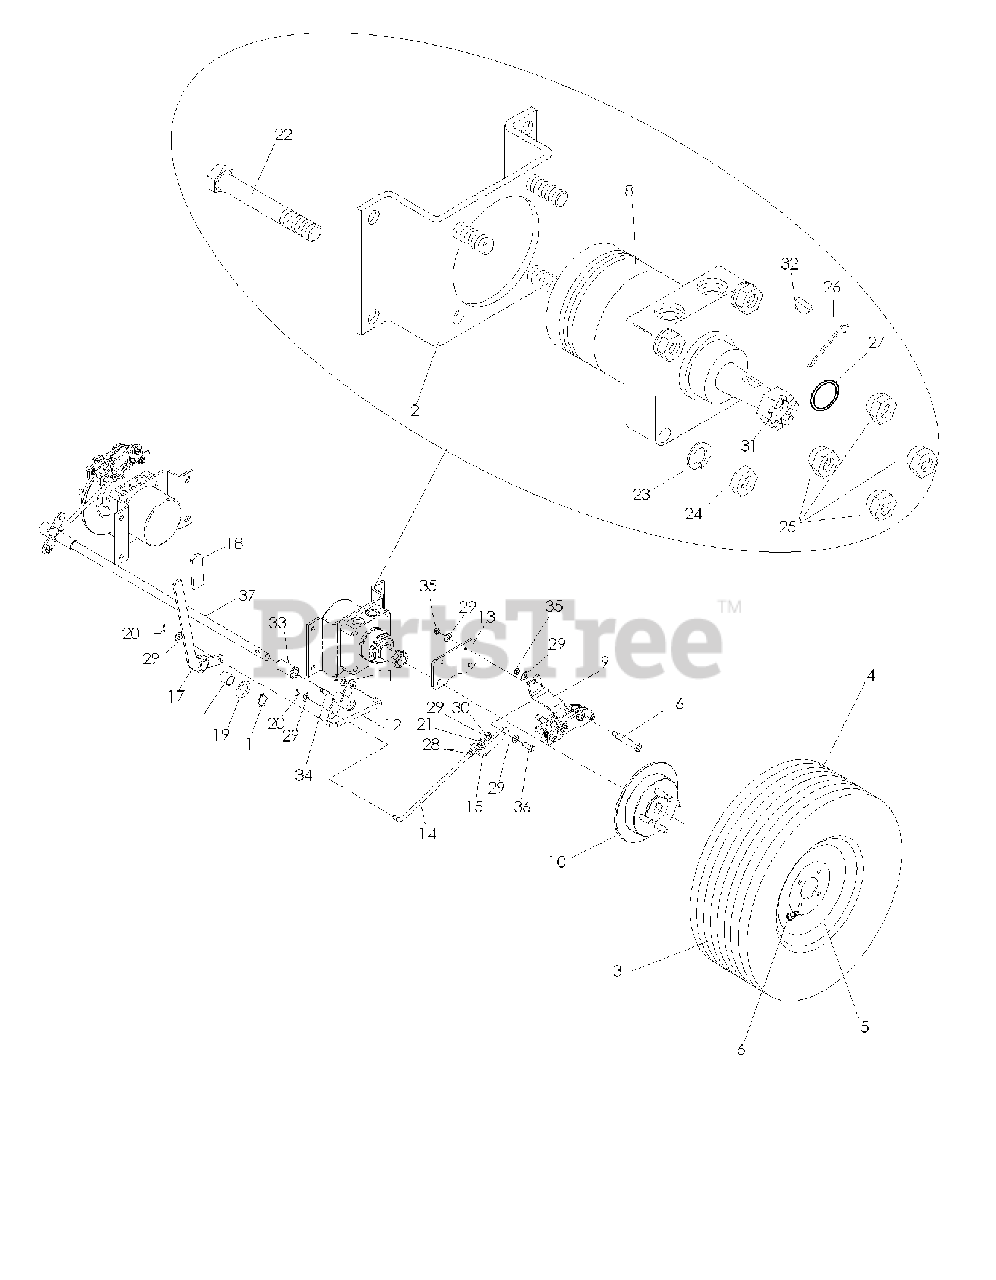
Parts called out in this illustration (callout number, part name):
1	RETAINING RING, 7/8"
2	MOTOR STANDOFF - PAINTED
3	TIRE ASSY 24-12
3	TIRE WHEEL ASM 23 X 9.5-12
4	TIRE.TURF.MASTER.24X12-12
5	RIM 2.5" NEG OFFSET 8.5" WIDE
6	VALVE STEM TR-412
7	BUSHING
8	TL15 WHEEL MOTOR
9	CALIPER ASSEMBLY
11	BELLCRANK, BRAKE
12	LINKAGE, BRAKE
13	PLATE, BRAKE
14	LINKAGE, REAR BRAKE
15	BRACKET, L
16	SB 3/8-16 X 2-1-1/2 SKT HDD ZD
17	LEVER, BRAKE WELDMENT
18	GRIP BRAKE HANDLE
19	BSHG .875 X 1.375 X .074 ZD
20	COTTER PIN 3/32 X 3/4
22	HCS 1/2C X 2 3/4
23	WASHER 1/2" SPLIT LOCK
24	NUT HEX 1/2
25	LUG NUT 1/2F
26	PIN COTTER 4MM X 45MM
27	MACHINE BUSHING
28	NUT 3/8-24 JAM
29	WASHER 3/8 SAE FLAT
30	NUT 3/8F CENTERLOCK
31	CASTLE-NUT
32	WOODRUFF KEY
33	BUSHING, POLYMER 3/4X2
34	5/16 DIA ROLL PIN
35	NUT HEX 3/8-16 NYLON, THIN
36	HCS 3/8C X 1
